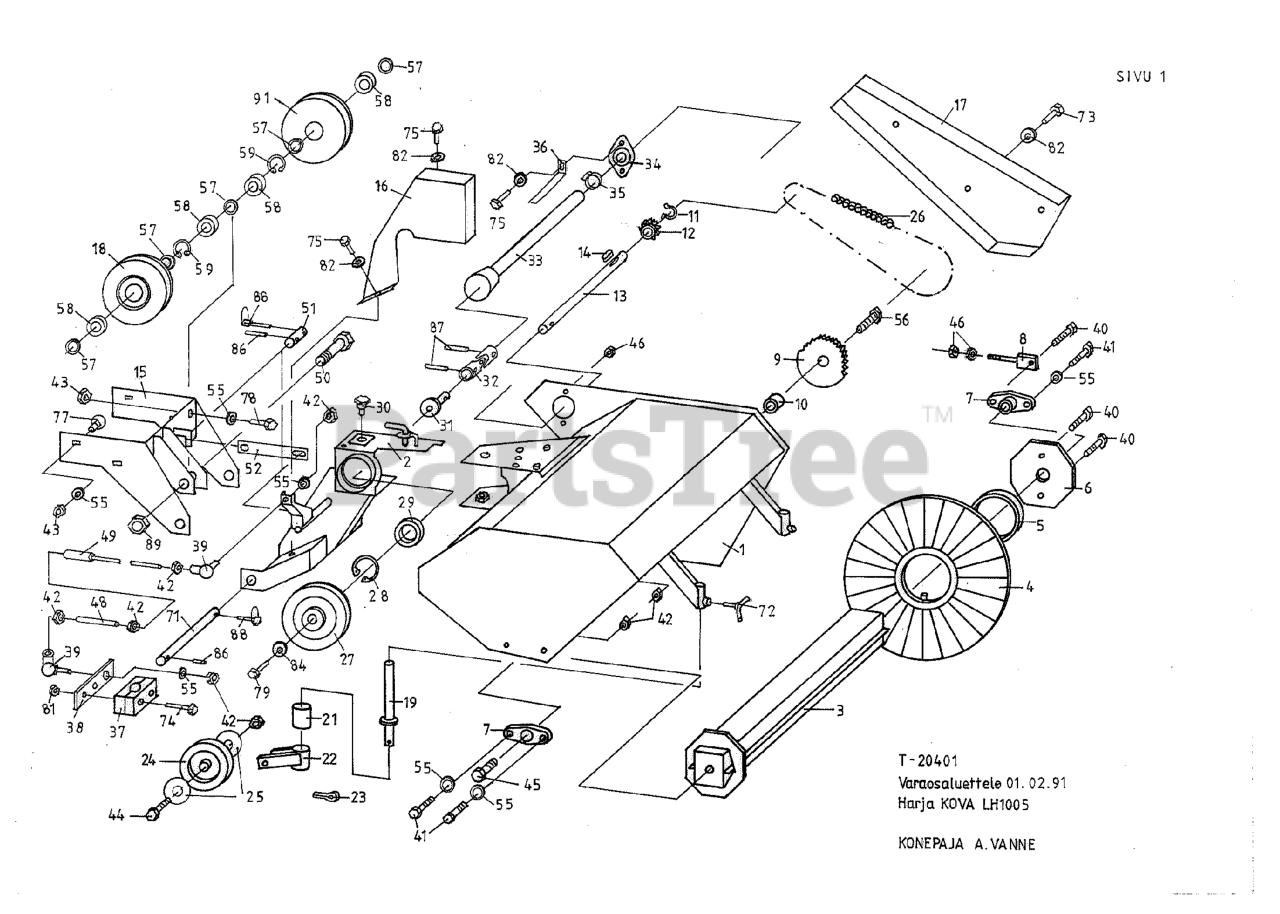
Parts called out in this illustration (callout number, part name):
4	BRUSHSEGMENT
5	WASHER BRUSHSEGMENT
7	BEARING UCFL 204
8	CHAINTIGHTNER
9	CHAINWHEEL
12	CHAINWHEEL
17	CHAINPROTECTOR
20	FRAME BRUSH
28	RETAINING RING
70	BELT TIGHTENER
92	BELT GUIDE
